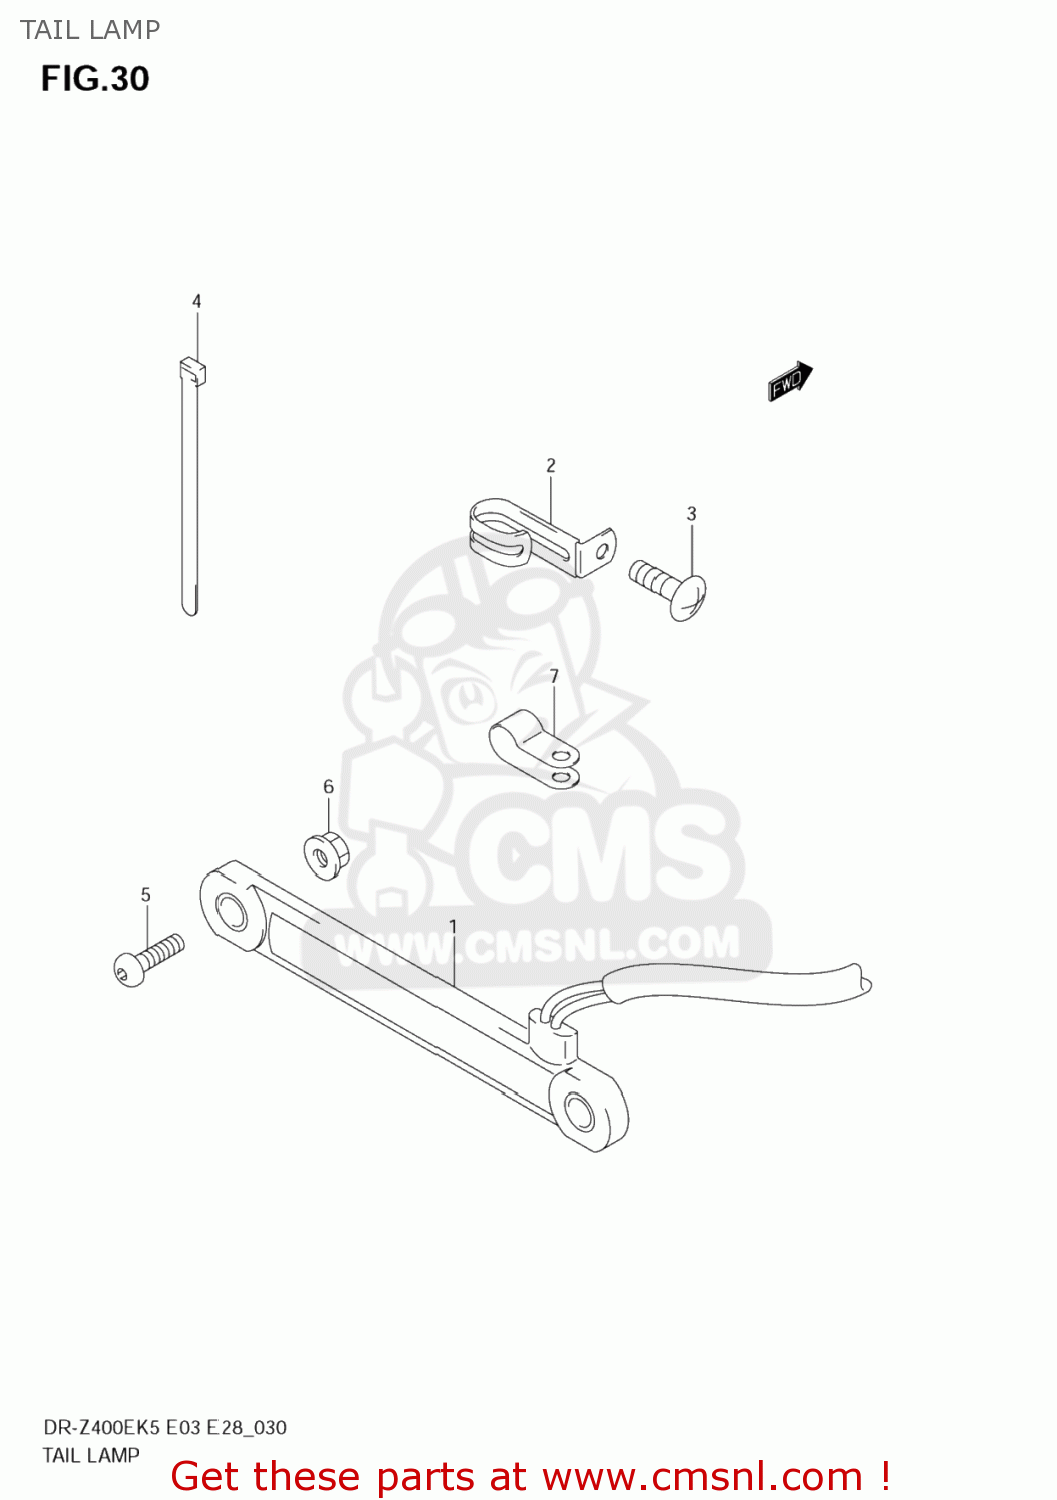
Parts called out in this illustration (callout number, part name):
1	LAMP ASSY,TAIL
2	CLAMP,TAIL LAMP LEAD
3	SCREW(5X18)
4	CLAMP(L:100)
5	SCREW
6	NUT
7	CLAMP
